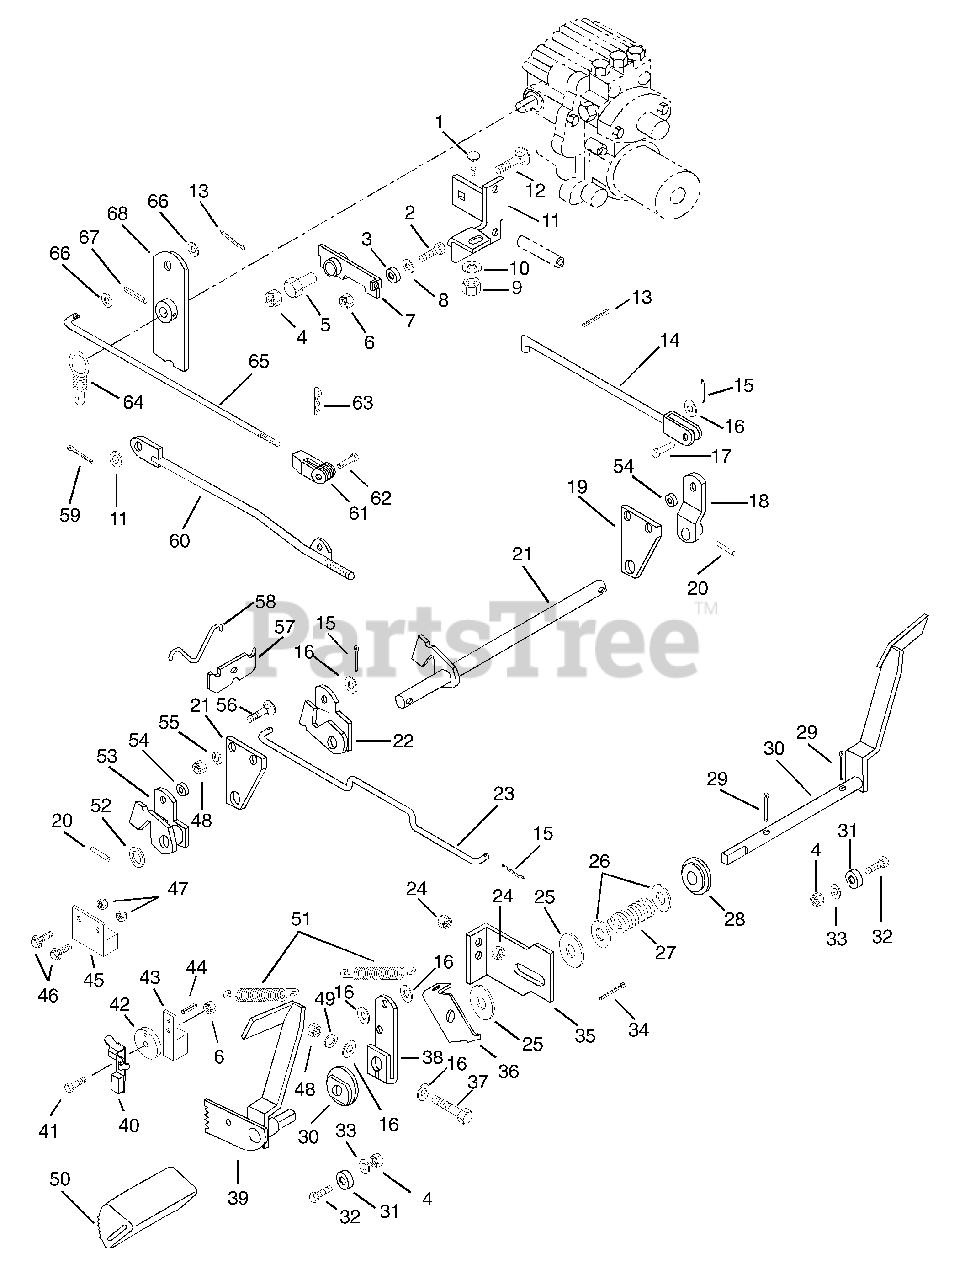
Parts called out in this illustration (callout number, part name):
1	BLT-RDHDSQNK .50-13X1.25 G2YW
2	@BLT-HEX .25-20X1.00 GR5 YWZC
3	BRG BALL DBL .250X.638X.438
4	@NUT-LK-CTR .31-18 YWZC
5	ECCENTRIC
6	@NUT-LK-CTR .25-20 YWZC
7	DETENT ARM
8	WSHR-FL-STL .281X1.250X.048 BL
9	NUT-LK-CONE .50-13 GR C YWZC
10	@WSHR-FL-STL.531X1.06X.095YWZC
11	MOUNT WELDMENT
12	@BLT-RDHDSQNK .31-18X2.25 G5YZ
13	@PIN-CTR .09X.75 EXTPRSQCT YWZ
14	BRAKE ROD
15	@PIN-CTR .12X.75 EXTPRSQCT YWZ
16	@WSHR-FL-STL.406X.812X.065 YWZ
17	PIN-CLEV .373X1.12 YWZC
18	BRAKE ARM
20	PIN-GRV .250X1.25 TP A
21	BRAKE SHAFT
23	BRAKE ROD
24	@NUT-LK-CTR .50-13 YWZC
25	WSHR-FL-STL .755X2.000X.125 YZ
26	WSHR-FL-STL.755X1.375X.062YWZC
27	SG-COMP .148X1.23X2.53 WLD87
28	BSHG-FLG .750X1.750X.875X2.125
29	@PIN-CTR .18X1.25 EXTPRSQCT YZ
30	L H LEVER
31	SPACER .344X1.000X.375
32	BOLT-HEX.31-18X.875 YWZC GR5
33	@WSHR-FL-STL.38X.875X.083 YWZC
34	@PIN-CTR .09X1.00 EXTPRSQCT YZ
35	NEUTRALIZER PLATE
36	NEUTRALIZER ARM
37	@BLT-HEX .38-16X2.25 GR5 YWZC
38	ARM-BRAKE
39	R H LEVER
40	BRAKE LOCK
41	@BLT-HEX .25-20X.75 GR5 YWZC
43	ACTUATOR,SWITCH
44	PIN-ROLL .125X.50
45	SWITCH, INTERLOCK NC
46	@SCR-MCH 10-24X.75 HWH YWZC
47	NUT-LK-DUAL FACE 10-24 YWZC
48	@NUT-HEX .38-16 YWZC
49	@WSHR-LK .38X.094 REG YWZC
50	PEDAL COVER
51	SG-TENS .090X.75X3.50 WLD 34
52	WSHR-FL-STL.754X1.125X.062YWZC
53	BRAKE ARM
54	GROMMET
55	WSHR-LK .375X.130 YWZC
56	@BLT-RDHDSQNK .38-16X1.00 G2YZ
57	BALANCE LINK
59	@PIN-CTR .12X1.00 EXTPRSQCT YZ
60	NEUTRALIZER ROD
61	YOKE, .312-24 X 2.25
62	PIN-CLEV .312X.822 HDND PL
63	PIN-HAIR INT .08X.18X1.18 YWZC
64	SG-TENS .080X.75X2.81 WLD 20
65	SHIFT ROD
66	WSHR-FL-STL .323X.625X.062 YWZ
67	PIN-ROLL .250X1.38
68	SHIFT ARM
